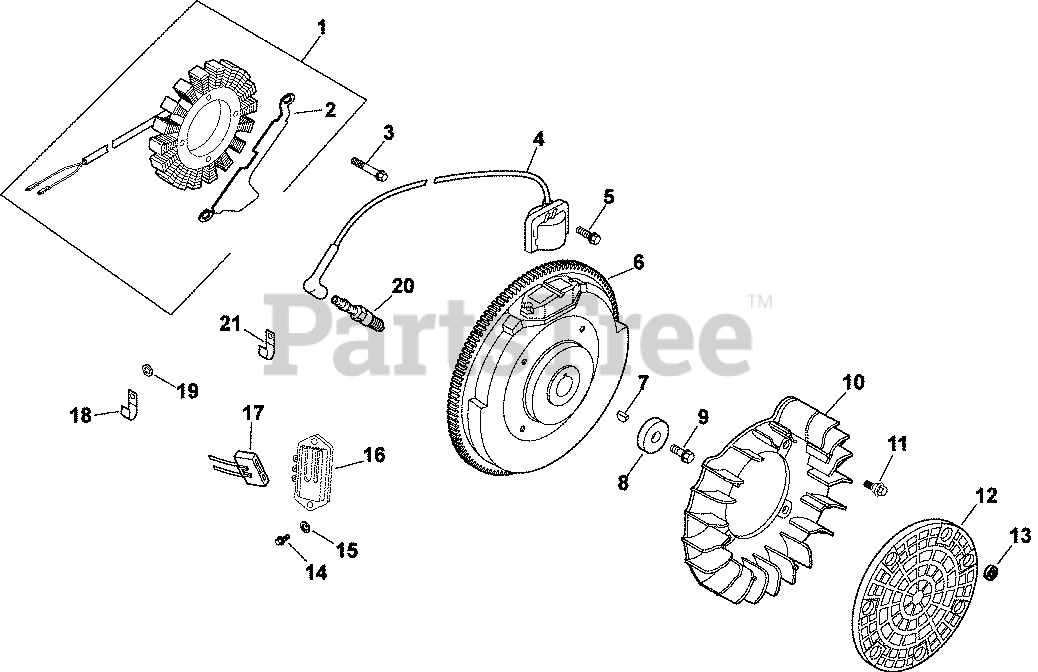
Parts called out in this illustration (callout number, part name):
1	STATOR ASSEMBLY 15/20A (KM)-USE 237878-S
2	BRACKET, STATOR WIRE-USE 24 126 139-S
3	SCREW, M5X0.8X25 - (#25086402S)
4	MODULE, IGNITION-USE 24 584 45-S
5	SCREW, FLG THD FRM M5X.8X20-(#25086399S)
7	KEY, 3/16" X 5/8"
8	WASHER, FLAT 13/32"
9	SCREW, FLG M10X1.5X45 - (#25086361S)
10	FAN (KM)-USE 24 157 15-S
11	BOLT, SHOULDER
12	SCREEN, GRASS
14	SCREW, PHL HD #11-16X7/8"
15	WASHER, FLAT 3/16"
17	CONNECTOR, BODY (KM)-USE 25 155 41-S
18	CLIP, CABLE
19	WASHER, FLAT 1/4" (O.D. 1/2")
20	PLUG, SPARK (STD)
2451809-S	LEAD, OIL SENTRY
